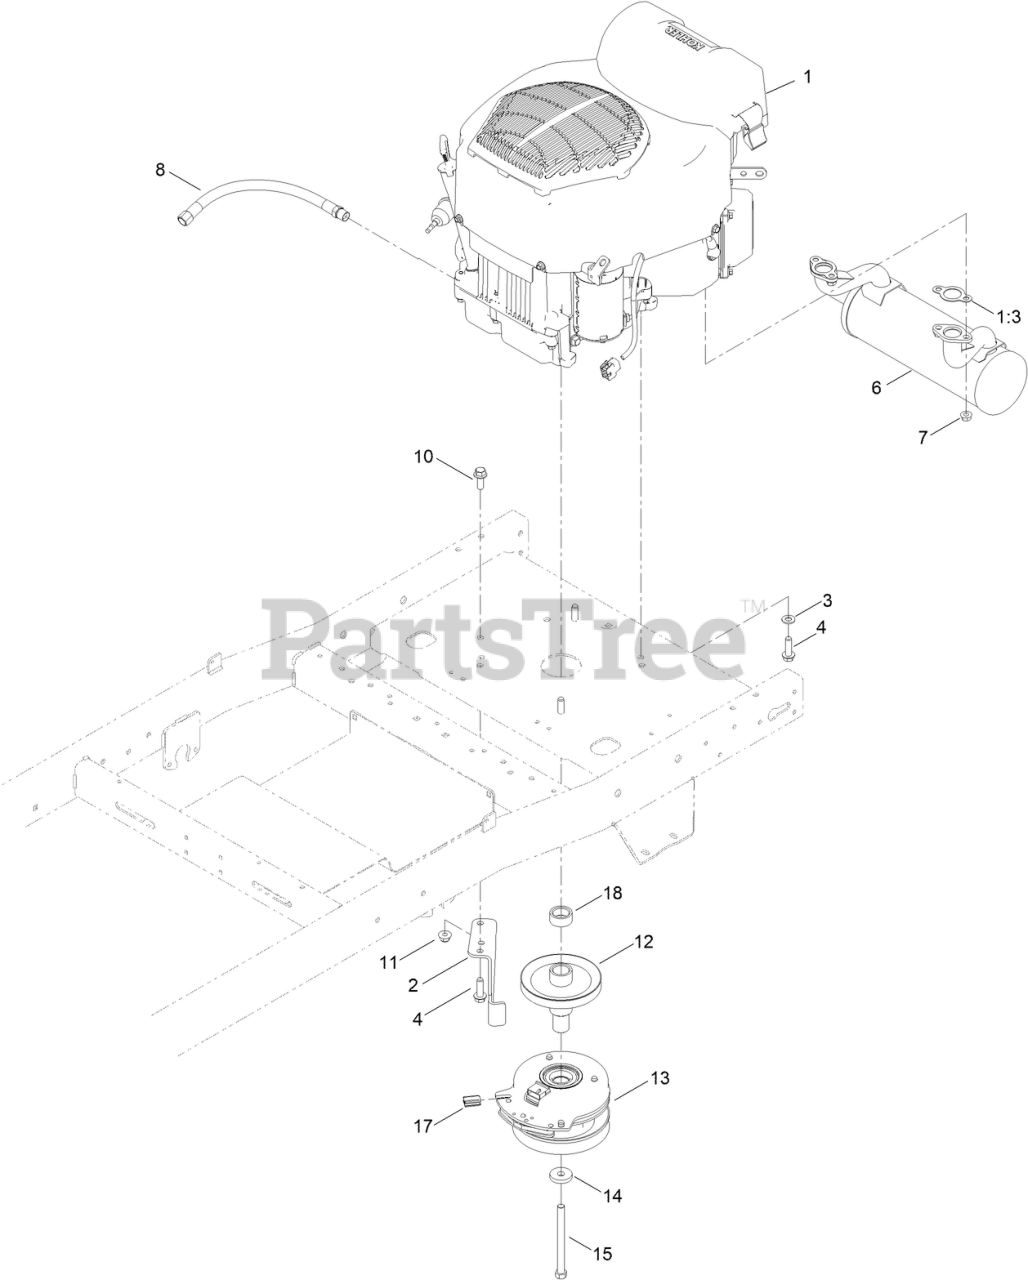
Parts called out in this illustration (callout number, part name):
1:3	GASKET-EXHAUST
2	STOP-CLUTCH (WIDE)
3	WASHER-FLAT
4	SCREW-THD
6	MUFFLER-KOHLER AES
7	NUT-HF
8	HOSE-DRAIN, OIL
10	SCREW-HHF
11	NUT-HF, NI
12	PULLEY-ENGINE
13	CLUTCH-PTO
14	WASHER
15	SCREW-HH
17	ISOLATOR-CLUTCH
18	SPACER-ENGINE PULLEY
